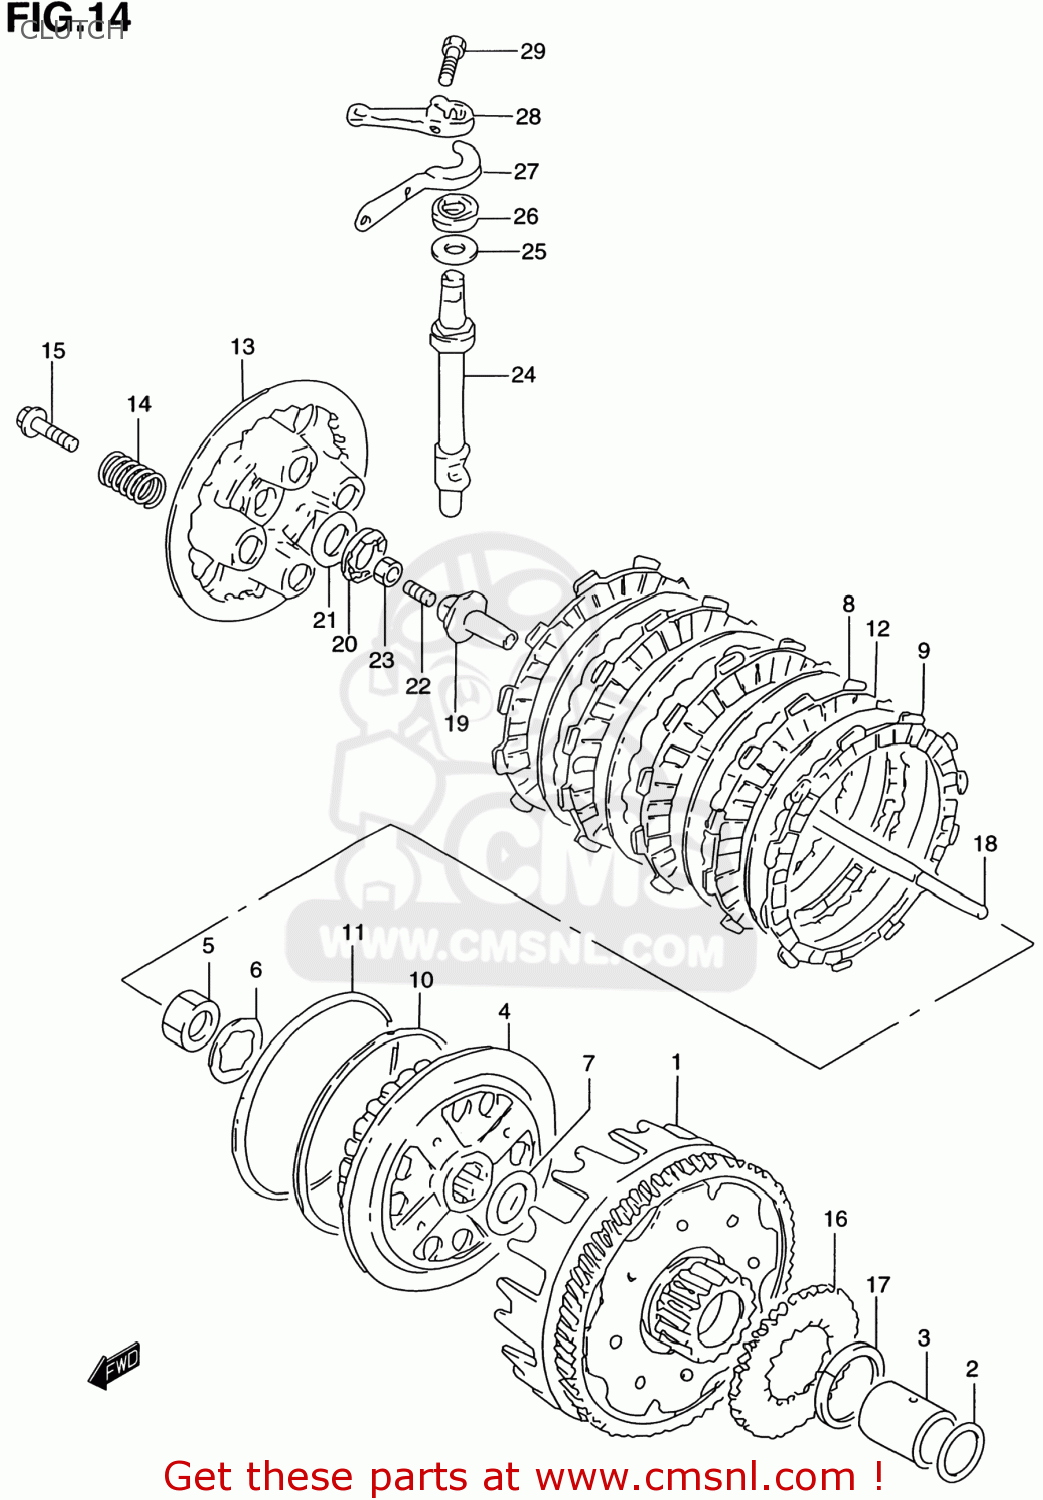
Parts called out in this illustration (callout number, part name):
1	GEAR ASSY,PRI DRIVEN
2	WASHER
3	SPACER(22X28X37.5)
4	HUB,CLUTCH SLEEVE
5	NUT
6	WASHER,LOCK
7	WASHER
8	PLATE,CLUTCH DRIVE (NAS)
9	PLATE,CLUTCH DRIVE(T:3.5) (NAS)
10	SEAT,WAVE WASHER(T:1.4)
11	WASHER
12	PLATE,CLUTCH DRIVEN(T:1.6) (NAS)
13	DISC,CLUTCH PRESSURE
14	SPRING,CLUTCH
15	BOLT(6X16)
16	GEAR,OIL PUMP DRIVE
17	CIRCLIP
18	ROD,CLUTCH PUSH
19	PIECE,CLUTCH PUSH
20	BEARING(15X28X2)
21	WASHER(15.5X28X1)
22	SCREW(6X25)
23	NUT
24	CAMSHAFT,CLUTCH RELEASE
25	WASHER(14.5X22X1)
26	OIL SEAL
27	PLATE,CLUTCH RRS CAMSHAFT SEAL
28	ARM,CLUTCH RELEASE
29	BOLT
